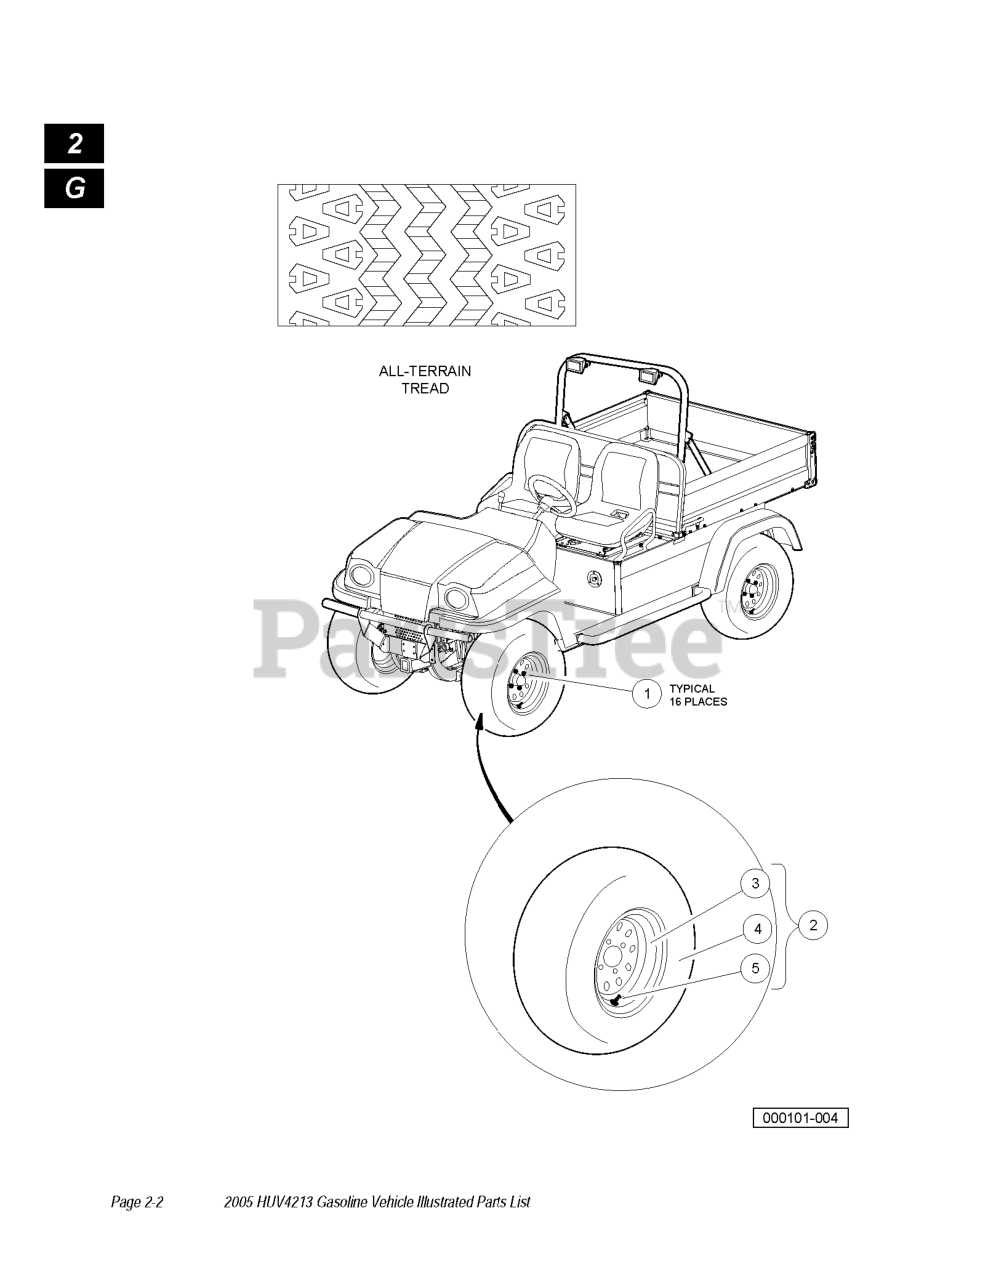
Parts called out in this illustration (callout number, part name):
1	NUT 1/2-20 LUG
2	Gray Tire Assembly, HDAT Tread
3	WHEEL RIM, GRAY
4	Tire, HDAT
